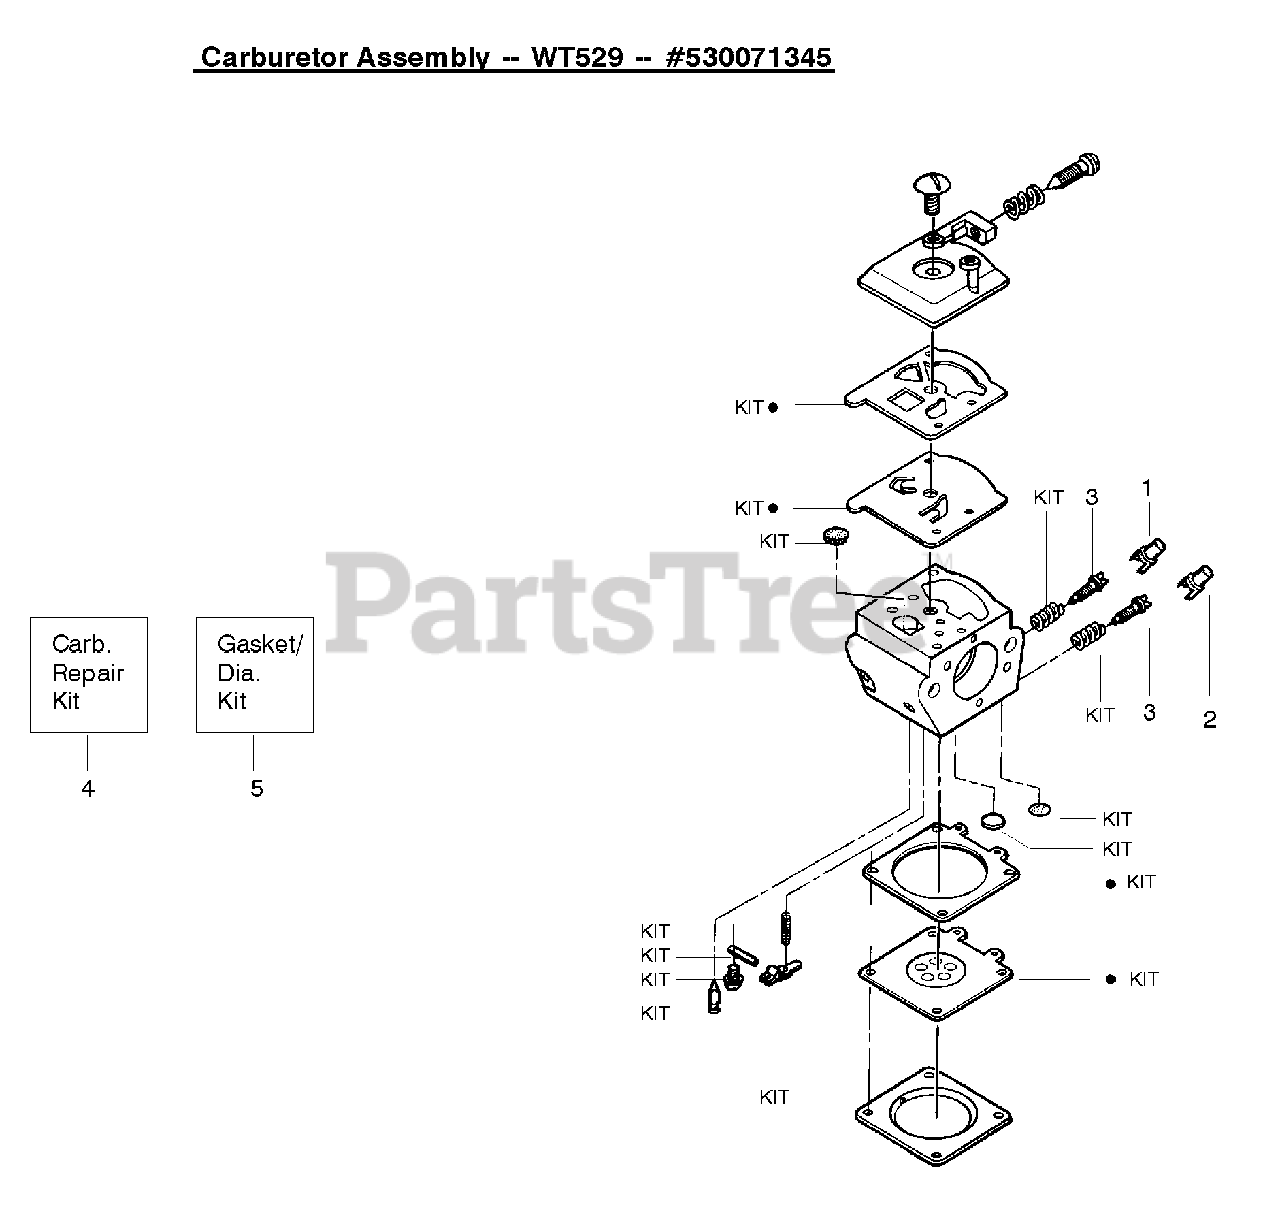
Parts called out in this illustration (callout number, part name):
1	Limiter-CapHigh
2	Limiter Cap-Low
3	Needle-High/low speed
4	Kit-Carburetor Repair
5	Kit-Gasket Diaphragm
